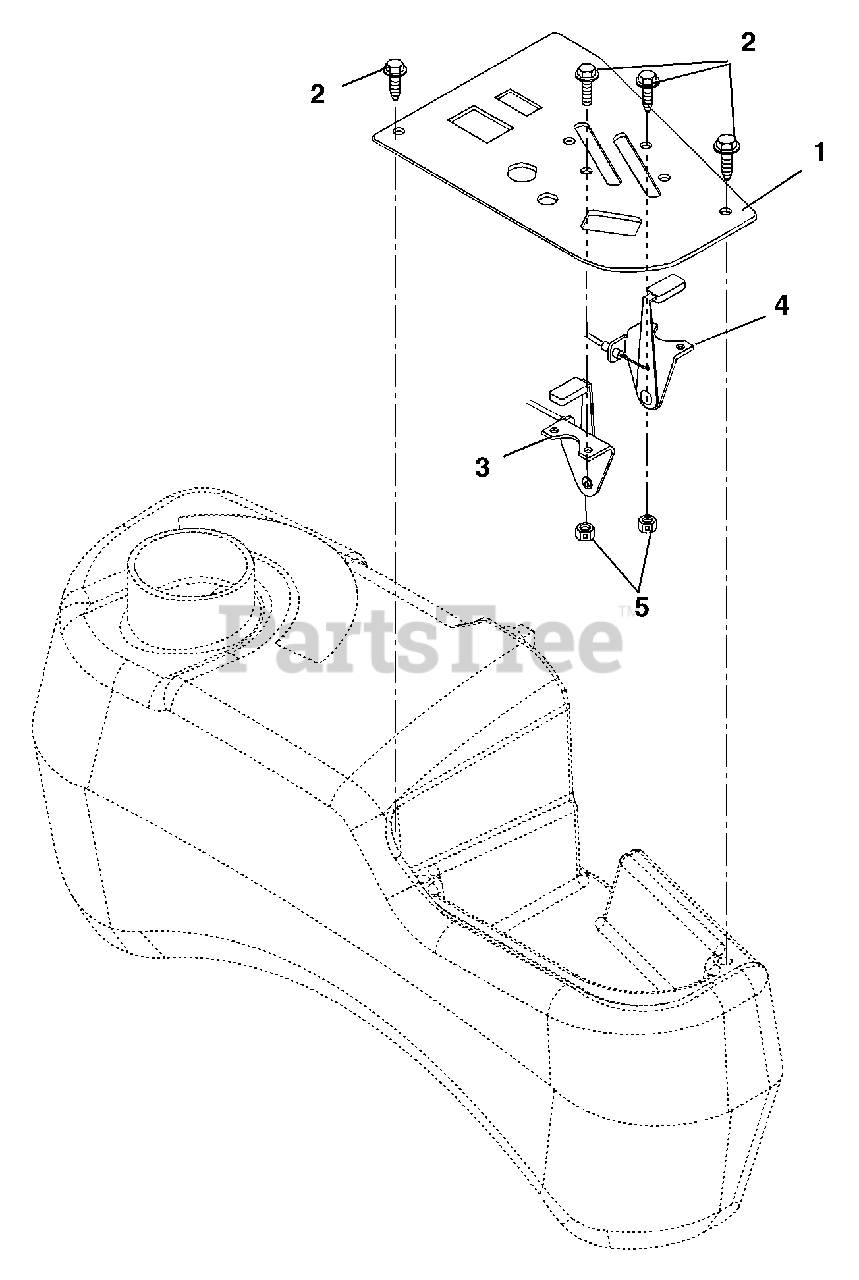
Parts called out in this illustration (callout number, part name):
1	Panel, Control
2	Screw, Machine 10-24 x .50 Hex Washer Head
3	Cable, Throttle
4	Cable, Kohler Choke (081, 082)
4	Cable, Choke, Kawasaki (077, 078, 079, 080, 310, 311)
5	Nut, Locking Nylon 10-24 With Insert
